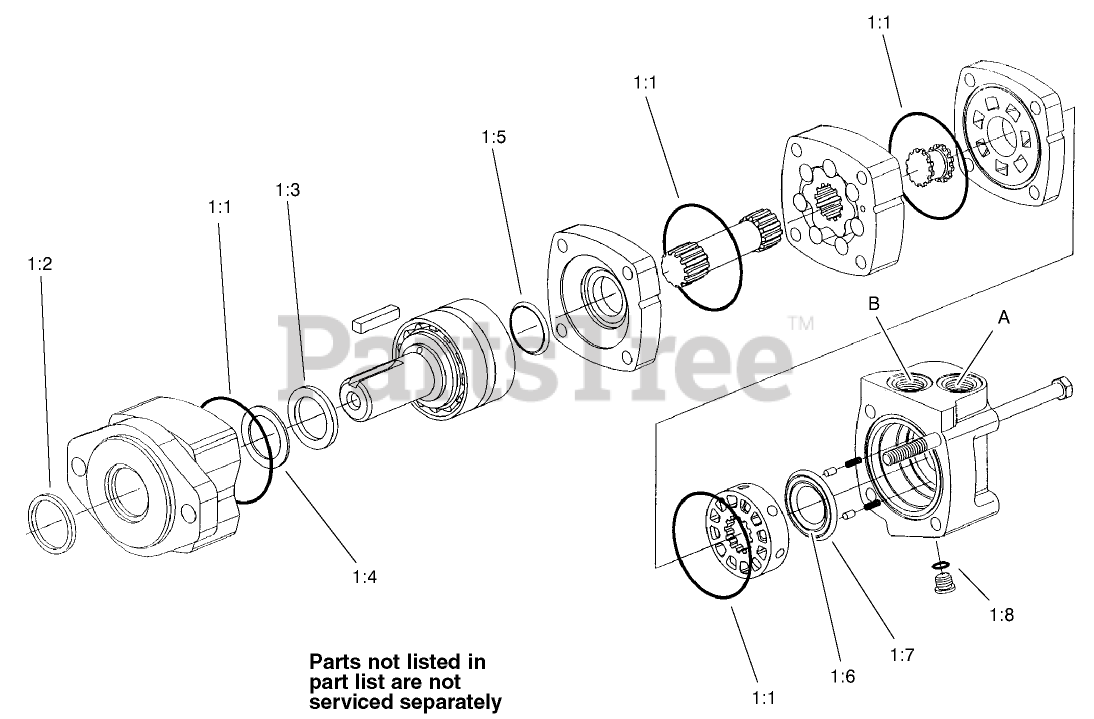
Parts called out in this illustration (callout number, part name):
1	SEAL KIT
1:1	Seal-Dust
1:2	Seal-Exclusion, Shaft
1:3	Seal-Shaft
1:4	Ring-Back-Up
1:5	Seal-Face, Shaft
1:6	Seal-Face, Inner
1:7	Seal-Face, Outer
1:8	Seal-Dust
